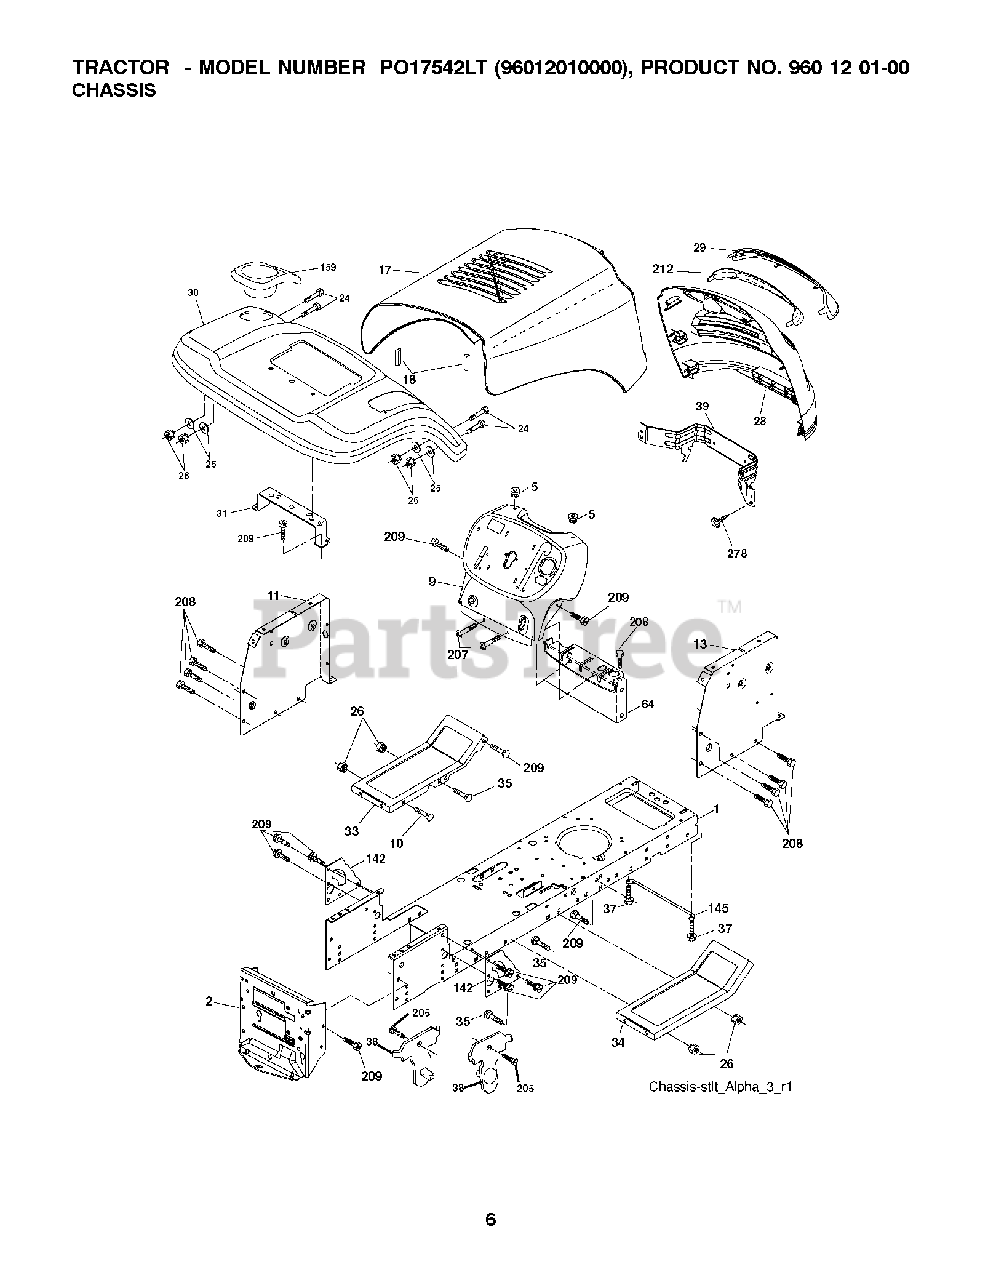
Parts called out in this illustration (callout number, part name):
1	CHASSIS STAMPING
2	DRAWBAR, 12GA
5	BUMPER.RUBBER.HOOD
11	PANEL.DASH.LH.LTX
17	HOOD.BLACK.ALPHA
18	BUMPER.HOOD.LARGE.1.75"
25	WASHER
26	NUT
28	GRILLE.ASM.ALPHA
29	LENS.ALPHA.BAR.LT
30	FENDER.LTST.W/SHFT.CUP.BLACK
31	BRACKET FENDER
33	FOOTREST.PNT.LH.BLACK
37	SCREW LT
38	BRACKET.ASM.PIVOT.MOWER.REAR
39	BRACKET.PIVOT.ALPHA.LT
64	DASH LOWER
142	PLATE REINFORCEMENT
145	ROD.PIVOT.HOOD
159	CUPHOLDER.BLACK
205	SCREW LT
207	SCREW, 5/16-18 X 1/2
208	SCREW 3/8-16X1/2
209	SCREW, 3/8-16X3/4
212	INSERT.ALPHA.REFLECTIVE.LT.
278	SCREW.#10 X 0.750.BOS (2 2)
